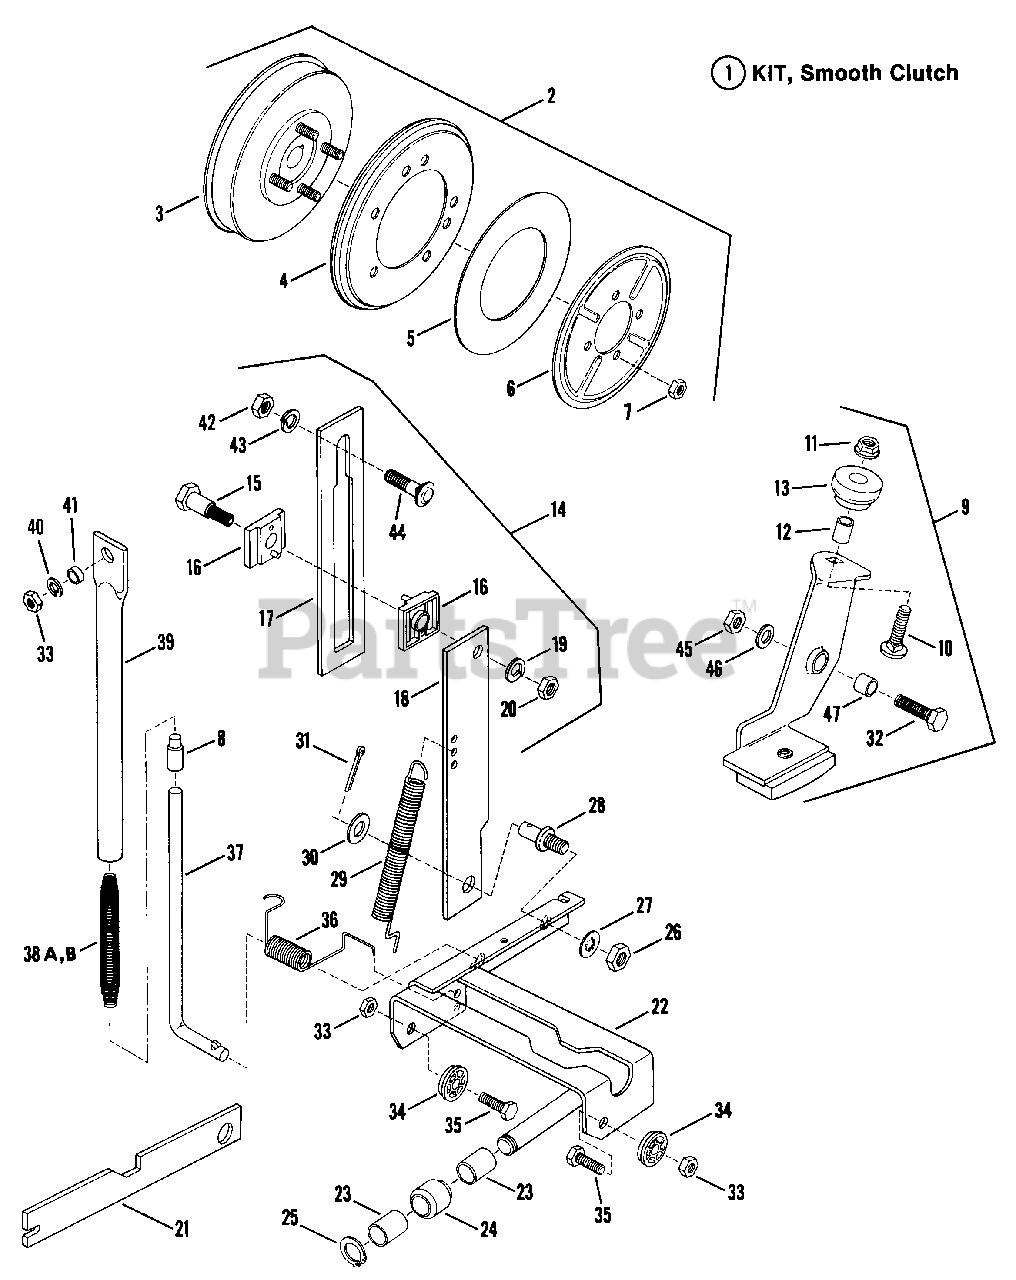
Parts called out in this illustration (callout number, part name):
1	KIT, Smooth Clutch
2	ASSEMBLY, Smooth Clutch
3	HUB, Driven Disc
4	DISC, Driven
5	WASHER, Thrust
6	PLATE
7	LOCKNUT, 5/16-18 Hex Flange
8	SPACER, Spring Plug
9	ASSEMBLY, Brake Lever
10	CARRIAGE BOLT, 1/4-20 x 1" Flat Head
11	LOCKNUT, 1/4-20 Hex Flange
12	BUSHING
13	ROLLER, Brake
14	ASSEMBLY, Guide L Link
15	BOLT, 5/16-18 Shoulder
16	SIDE HALF
17	GUIDE, Clutch Link
18	LINK, Clutch
19	LOCKWASHER, 5/16 Split
20	NUT, 5/16-18 Hex
21	TOOL, Smooth Clutch
22	LIFT, Yoke
23	SPACER, Roller
24	ROLLER, Park Brake
25	RING, Retaining
26	NUT, 3/8 Hex
27	LOCKWASHER, 3/8 Internal Tooth
28	STUD, Clutch Link
29	SPRING, Clutch Brake
30	WASHER, 3/8" Flat
31	COTTER-PIN, 3/32 x 1"
32	CAPSCREW, 1/4-28 x 1" Hex Head
33	NUT, 5/16-24 Hex Center Lock
34	BEARING, Yoke
35	CAPSCREW, 5/16-24x3/4" Hex Head
36	SPRING
37	ROD
38A	SPRING, 25 Coils
38B	SPRING, 34 Coils
40	LOCKWASHER, 5/16 Split
41	ROLLER
42	NUT, 3/8-16 Hex
43	LOCKWASHER, 3/8 Split
44	CARRIAGE BOLT, 3/8-16 x 3/4
45	LOCKNUT, 1/4-28 Hex
46	WASHER, 1/4 SAE
47	SPACER
